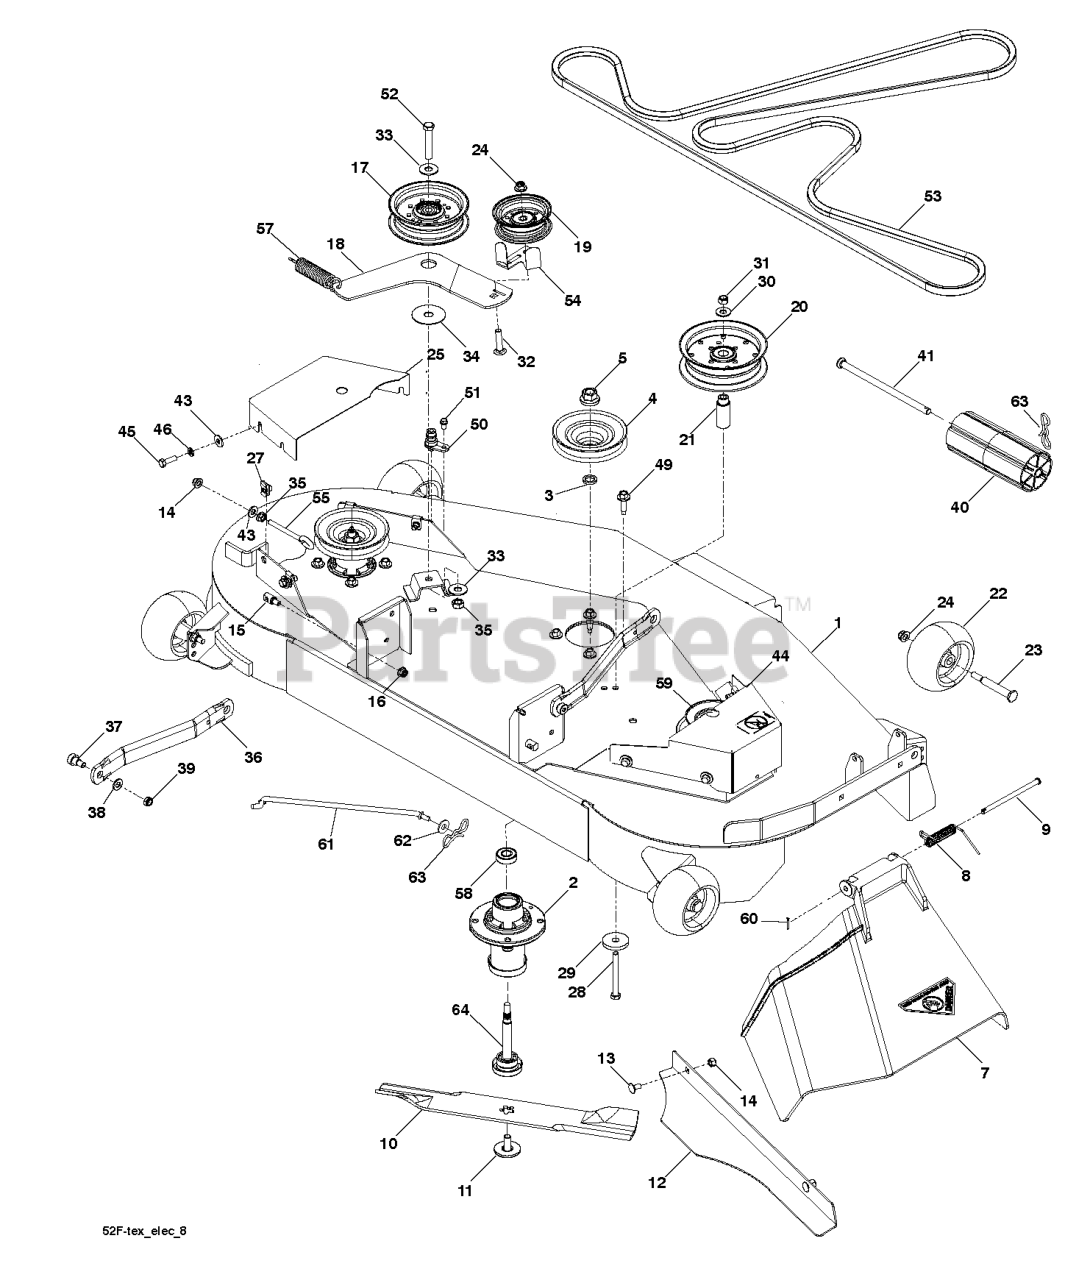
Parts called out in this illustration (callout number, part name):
1	DECK SVC W/DECALS.52.GTH.ORG
2	MANDREL ASM, CAST IRON
3	WASHER.SPACER.MANDREL
4	PULLEY.DRIVEN.DECK.48'
5	NUT.FLANGE.LOCK.TOP
7	DISCHARGE.CHUTE-52"
8	SPRING - TORSION
9	PIN, CLEVIS 5/16 X 5.19
10	BLADE, 17.75 X 2.5 X .25
11	BLADE BOLT ASSY-7/16" TB REPL
12	PLATE.52".CONFINEMENT.BLACK
13	BOLT.CARR.5/16-18X5/8.SHORT
14	NUT.71038.31-18.HEX.NYLOCK
15	STUD.FASTNER.W/ANTI-ROTATE
16	NUT LOCK FLG 3/8-16 UNC
17	PULLEY.IDLER.MWR.STATI.LH
18	ARM, IDLER, 52" BLK
19	PULLEY.IDLER.FLAT
20	PULLEY, IDLER
21	BUSHING, IDLER
22	WHEEL GAGE DONUT
23	BOLT.SHOULDER.3/8-16X3-5/8.
24	NUT 3/8-16 HEX FLG NYLOC ZD
25	SHIELD.BELT.LH.ORANGE
27	U-CLIP 5/16-18 NUT RETAINER
28	HCS 3/8-16 X 3-1/2 GR5 ZD
29	SPINDLE WASHER
30	RP WASHER 3/8 FLAT
31	NUT 3/8-16 NYLOC
32	RHSNB 3/8-16X1-3/4
33	WASHER 7/16 FLAT ZD
35	NUT.LOCK.FLANGE.7/16
36	ARM.SUSPENSION.MOWER
37	SB 3/8-16 X 3/8 SKT HD ZD
38	WASHER
39	NUT HEX 3/8-16 NYLON, THIN
40	NOSE ROLLER 48"
41	ROD.ROLLER.NOSE.NARROW.48"
43	WASHER.5/16.FLAT.STE.STD.
44	SHIELD.BELT.RH.52.ORANGE
45	BOLT.FIN.HEX.5/16-18UNC X 1.00
46	WASHER.LOCK.HVY.HLCL.SPR.5/16
49	BOLT.HEX.WASHR.HED.313-18X1.19
50	PORT.WASHOUT
51	SCREW
52	BOLT.HEX.7/16-14
53	BELT, 143.5" EL
54	GUARD, BELT
55	EYE BOLT 5/16 X 3.50
59	RP PULLEY, COLLECTION 48
60	RETAINER CLIP
61	ROD.ANTI.SWAY.48/54"TE
62	WASHER
63	PIN.COTTER.5/16.BOW TI
64	SHAFT ASM MANDREL
